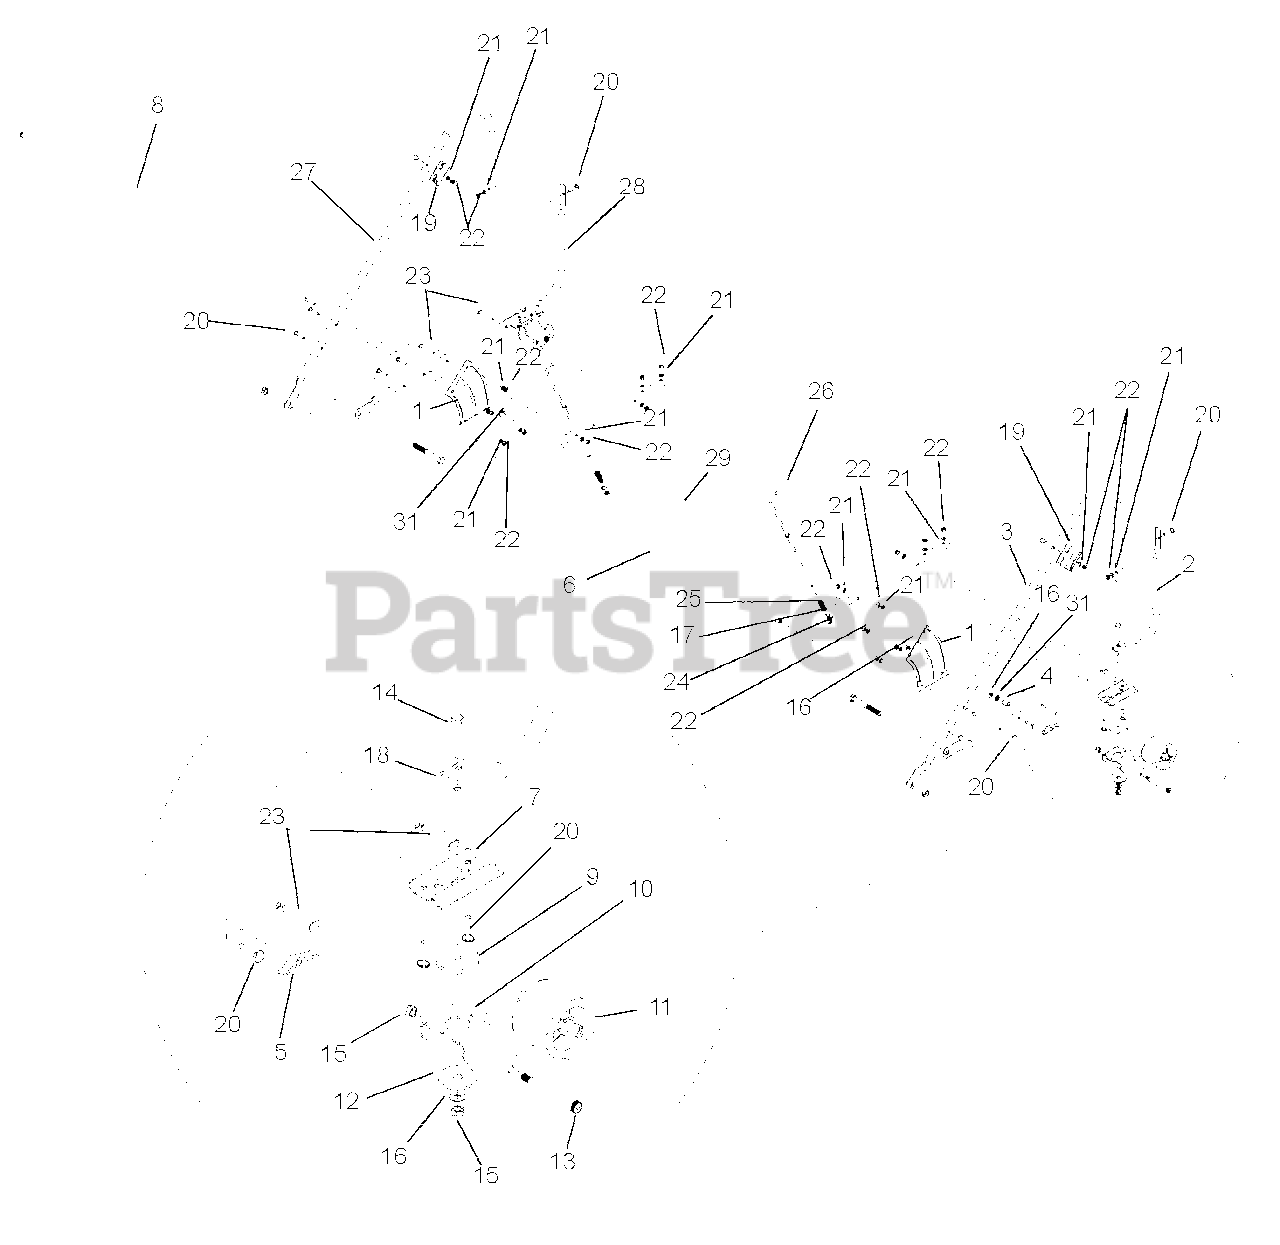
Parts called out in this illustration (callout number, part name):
1	Plate, Adjuster
2	Frame Support, Lower
3	Frame Support, Upper
4	Spacer, .500 OD X .625 L
5	Wing Nut
6	Rod Pivot, 43-1/8
7	Plate, Caster
8	Bolt, Adjuster 44-5/8
10	Caster Fork
12	Washer, Area Vac 35 29/64 X 1-3/4 X .134
13	Bolt, Shoulder Socket 3/8 X 2-3/4
14	Bolt, Hex .31-18 X 2.00 Gr 5 YWZC
15	Nut, Nylok .312-18 YWZC
16	Washer, Flat Steel .344 X .688 X .065 YWZC
17	Washer, Flat Steel .281 X .62 X .065 YWZC
19	Bracket, Pivot
20	Bolt, Contour Head 1/4-20 X 1.25
21	Washer, Lock .25 X .062 Reg YWZC
22	Nut, Hex .25-20 YWZC
23	Bolt, Contour Head 1/4-20 X 2.0
24	Nut, Speed 1/4
25	Spring, Compression
26	Basket Stop Weldment
27	Frame Support, Upper
28	Frame Support, Lower
29	Frame Support, 74-3/8
30	Washer, Lock Internal Star 3/8 YWZC
31	Washer, Flat Steel .438 X 1.00 X .083 YWZC
